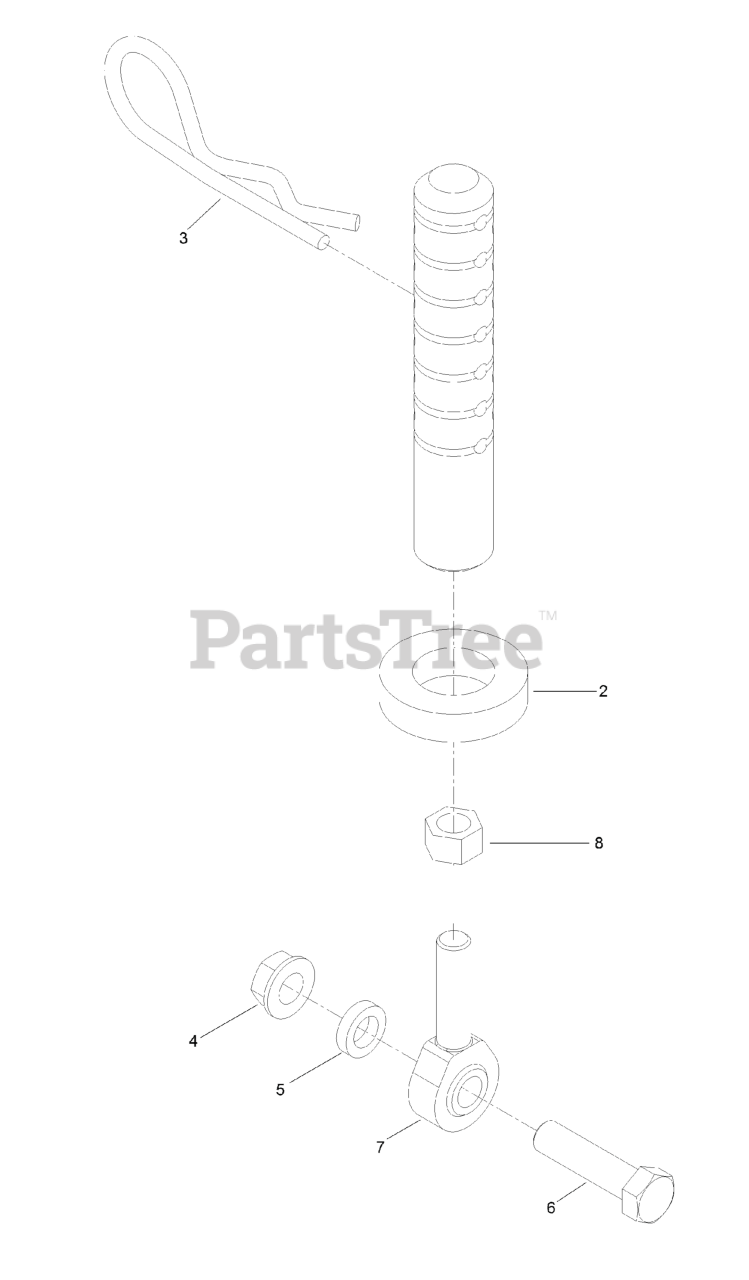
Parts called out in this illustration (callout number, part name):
2	SPACER-DECK SUPPORT
3	PIN-CUT HEIGHT
4	NUT-HHF, WHIZ
5	SPACER-IDLER
6	SCREW-HH
7	BALLJOINT
8	NUT-HJ
